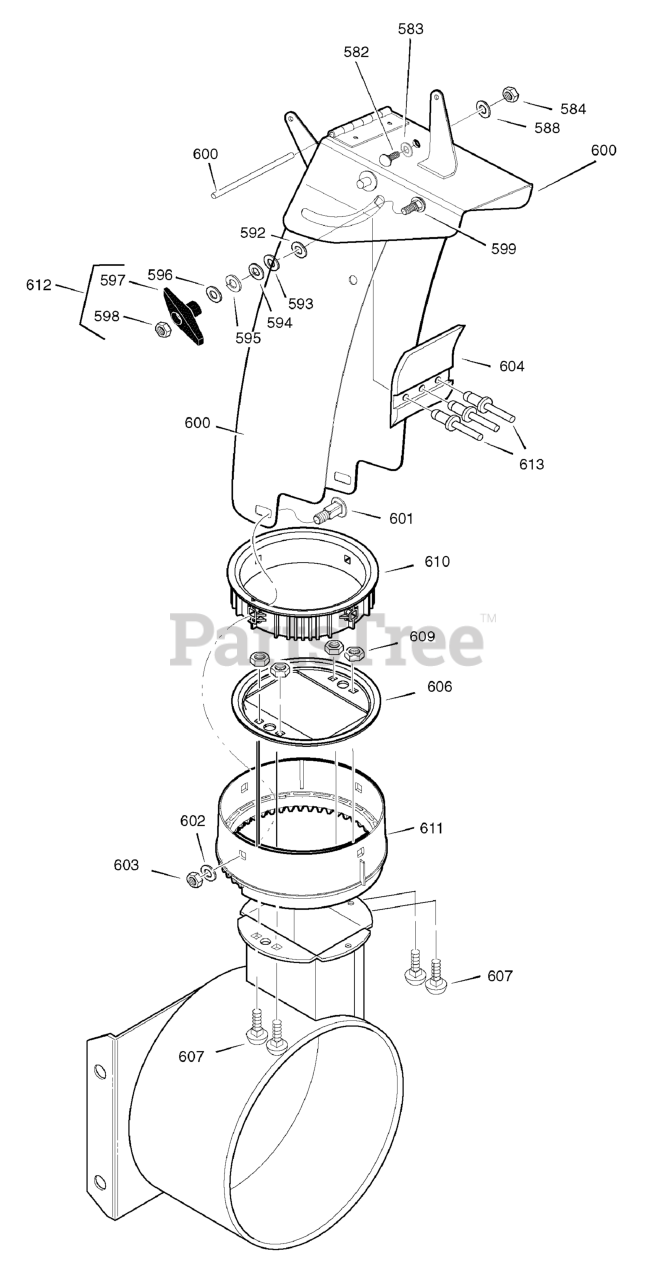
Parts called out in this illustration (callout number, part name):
582	BOLT, Carriage, 5/16 - 18 x 3/4
583	WASHER, Plastic
584	NUT, Hex Nylock, 5/16 - 18
588	WASHER, Plastic
592	WASHER, Plastic
593	WASHER, Plastic
594	WASHER, Flat
595	WASHER, Split
596	WASHER, Flat
598	NUT, Hex, 5/16 - 18
599	BOLT, 5/16 - 18 x 1
600	CHUTE ASSEMBLY
601	BOLT, Carriage, 5/16 - 18 x 1
602	WASHER, Flat
603	NUT, Hex Nylock, 5/16 - 18
604	FLAP, Chute
606	CHUTE COLLAR
607	SCREW, 1/4 - 20 x 3/4
609	NUT, Hex Nylock, 5/16 - 18
610	RETAINER RING, Inner
611	RETAINER RING, Outer
612	KNOB & NUT
613	RIVET, Pop
